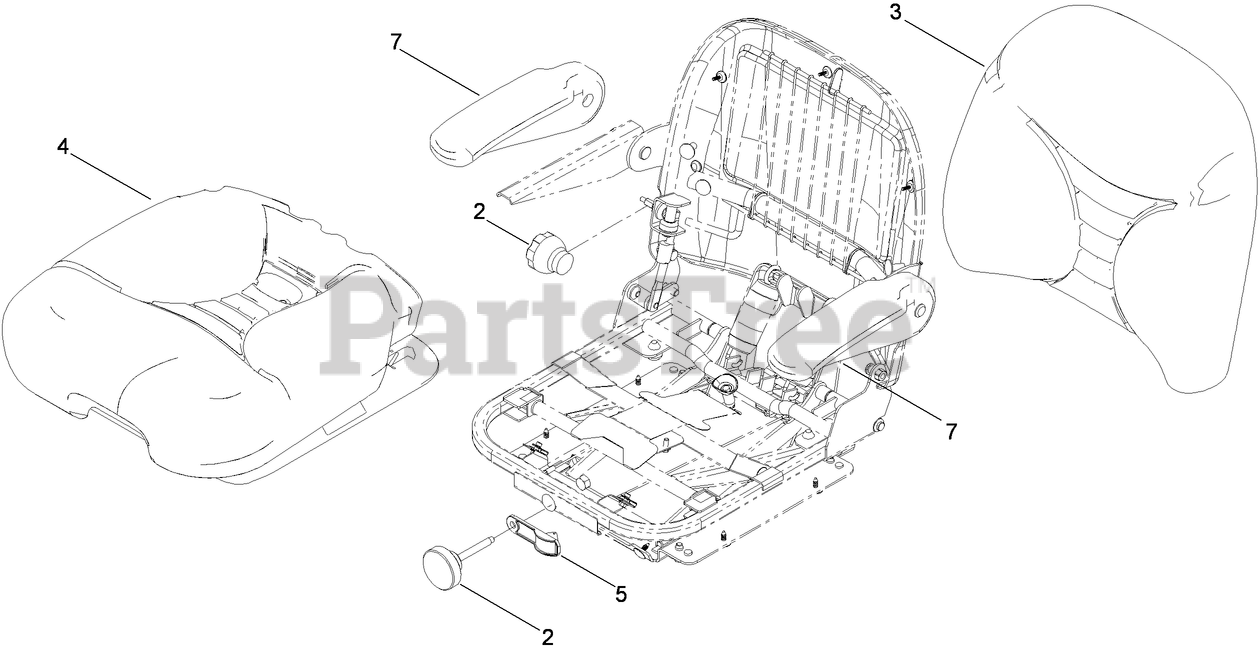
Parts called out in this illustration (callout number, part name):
2	Knob Kit
3	Back Cushion Kit
4	Bottom Cushion Kit
5	Weight Indicator Kit
7	PAD-ARMREST
